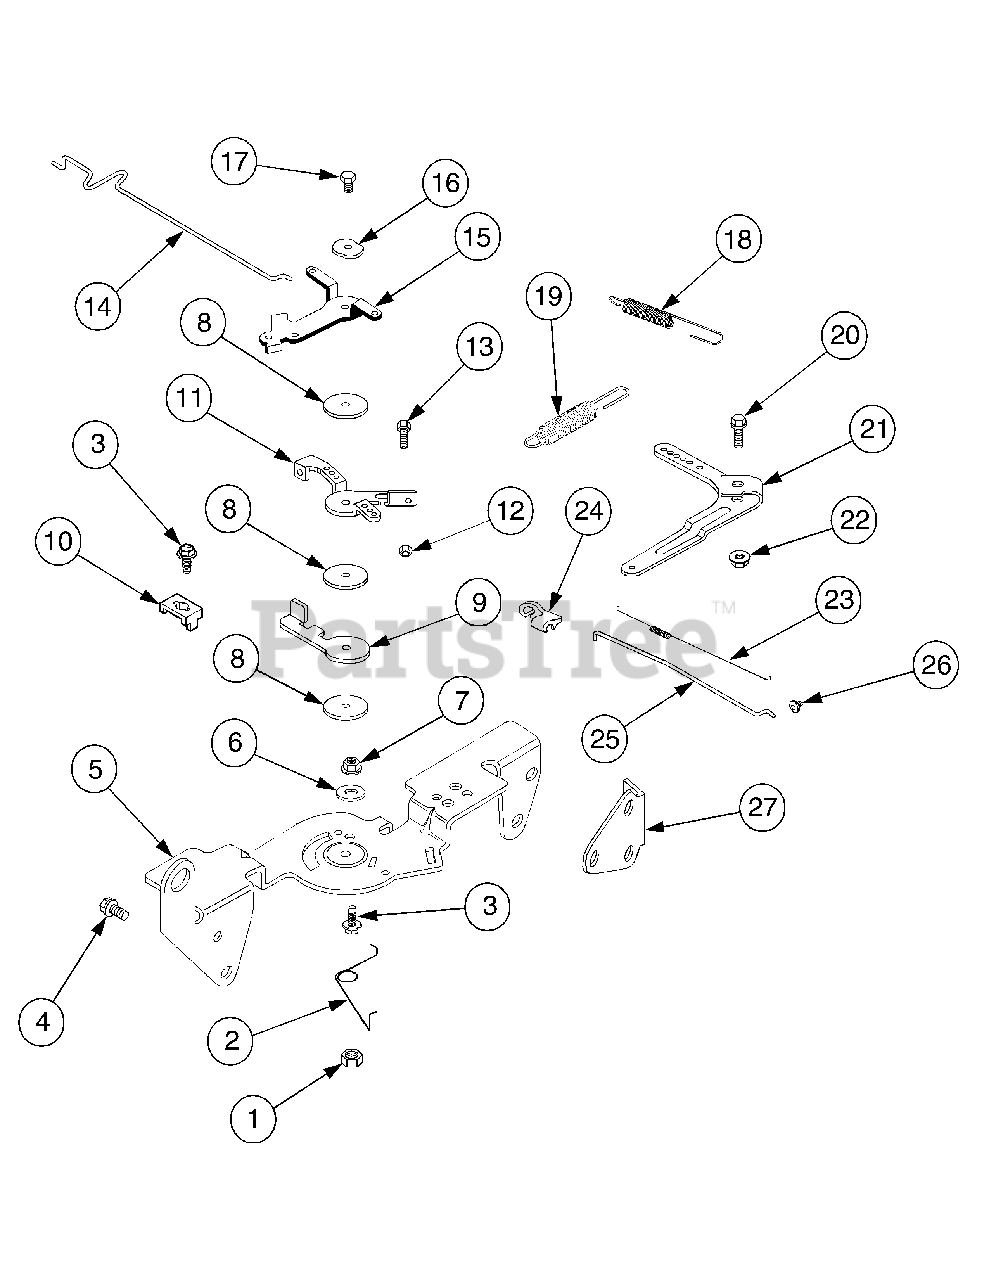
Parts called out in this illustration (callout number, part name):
1	Nut, Hex Lock M5 x 0.8
2	Spring, Choke Return
3	Screw, Hex Flange M6 x 1.0 x 16
4	Screw, Hex Flange M5 x 0.8 x 16
5	Bracket, Control
8	Washer , Plain 5.5mm
9	Lever, Throttle Actuator
10	Clamp, Cable
11	Lever, Throttle Control
12	Nut, Hex M4 x 0.7
13	Screw, Hex Cap M4 x 0.7 x30
14	Linkage, Choke
15	Lever, Choke
16	Washer, Spring 1/4"
17	Screw, Hex Flange M5 x 0,.8 x 20
18	Spring, Throttle Limiter
19	Spring, Governor
20	Screw, Round Hd. Square Neck
21	Lever, Governor
22	Nut, Hex Flange M6 x 1.0
23	Spring, Linkage
24	Bushing, Linkage Retaining
25	Linkage, Throttle
26	Bushing, Linkage Retaining
27	Bracket, Support
